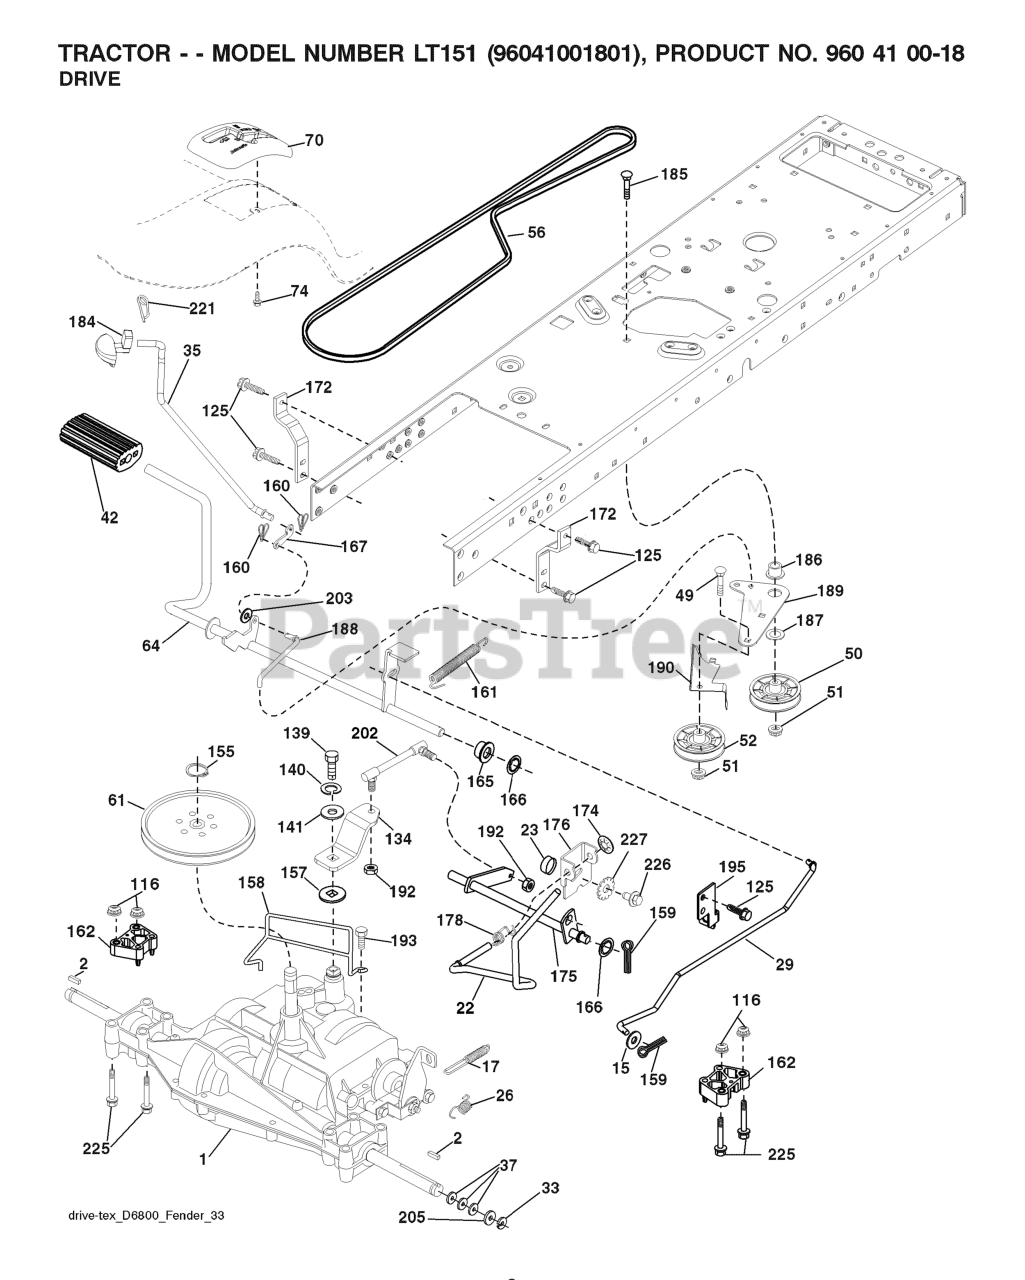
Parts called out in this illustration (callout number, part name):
2	SQUARE KEY
15	WASHER
17	SPRING.BRAKE.PEERLESS.TEX
22	ROD.SHIFT.FENDER.TLT.2006
23	KNOB.DUCKHEAD.1/2
26	SPRING.BRAKE.RTN.GR.DR
29	ROD.BRAKE.PEERLESS
35	ROD.CNTRL.PARK.PREDATOR.LT.TEX
42	PEDAL COVER T
50	IDLER.FLAT.910.OFFSET
51	NUT LOCK FLG 3/8-16 UNC
52	IDLER.V-GROOVE.910.OFFSET
56	V-BELT.TRACTOR.DRIVE.P
61	PULLEY TRANS
64	SHAFT.ASM.PEDAL.BRAKE.
70	CONSOLE.SHIFT.STL.6SP.GREY
74	SCREW.HI-LO.CONSOLE
116	NUT LOCK HEX FLANGE 5/16-18
125	SCREW
139	BOLT 1/4-28X3/4
140	LOCKWASHER
155	RETAINING RING LT
157	WASH-SHFT PLT LT
158	KEEPER.PMS.18/20.D4365
159	COTTER PIN
160	RETAINER CLIP
161	SPRING.RETURN.CLUTCH.2006
162	SPACER.TRANSAXLE.18&22
165	BUSHING.SHAFT.BRAKE.HAND
166	NUT.PUSH.625.2006
167	LATCH.BRAKE.SPRING
172	STRAP.TRQ.LH.GEAR.DRIV
174	NUT.PUSH.500.2006
175	SHAFT ASM SHIFT
176	ARM.CLEVIS.ROD.SHIFT
178	SPRING.SHIFT.GT2006
183	SPACER AXLE
184	HANDLE PARKING BRAKE
186	SPACER.RETAINER
187	WASHER 12/32X2X10GA
188	RP.LINK.CLUTCH.GROUND.DRIVE
189	BELLCRANK.GROUND.DRIVE.TEX.
190	KEEPER.BELLCRANK.DRIVE
192	NUT LOCK CENTER 1/4 -28 FNTHD
193	SCREW 5/16"
195	BRKT.ROD.BRAKE.PEERLES
202	LINK.TRANSAXLE.PMST/DANA.20"
203	WASHER
221	RETAINER.SPRING.CLIP.H
225	BOLT.HEX.FLNG.5/16-18X3.75
226	BOLT FIN HEX 7/16-14 X 1
227	WASHER SERRATED
